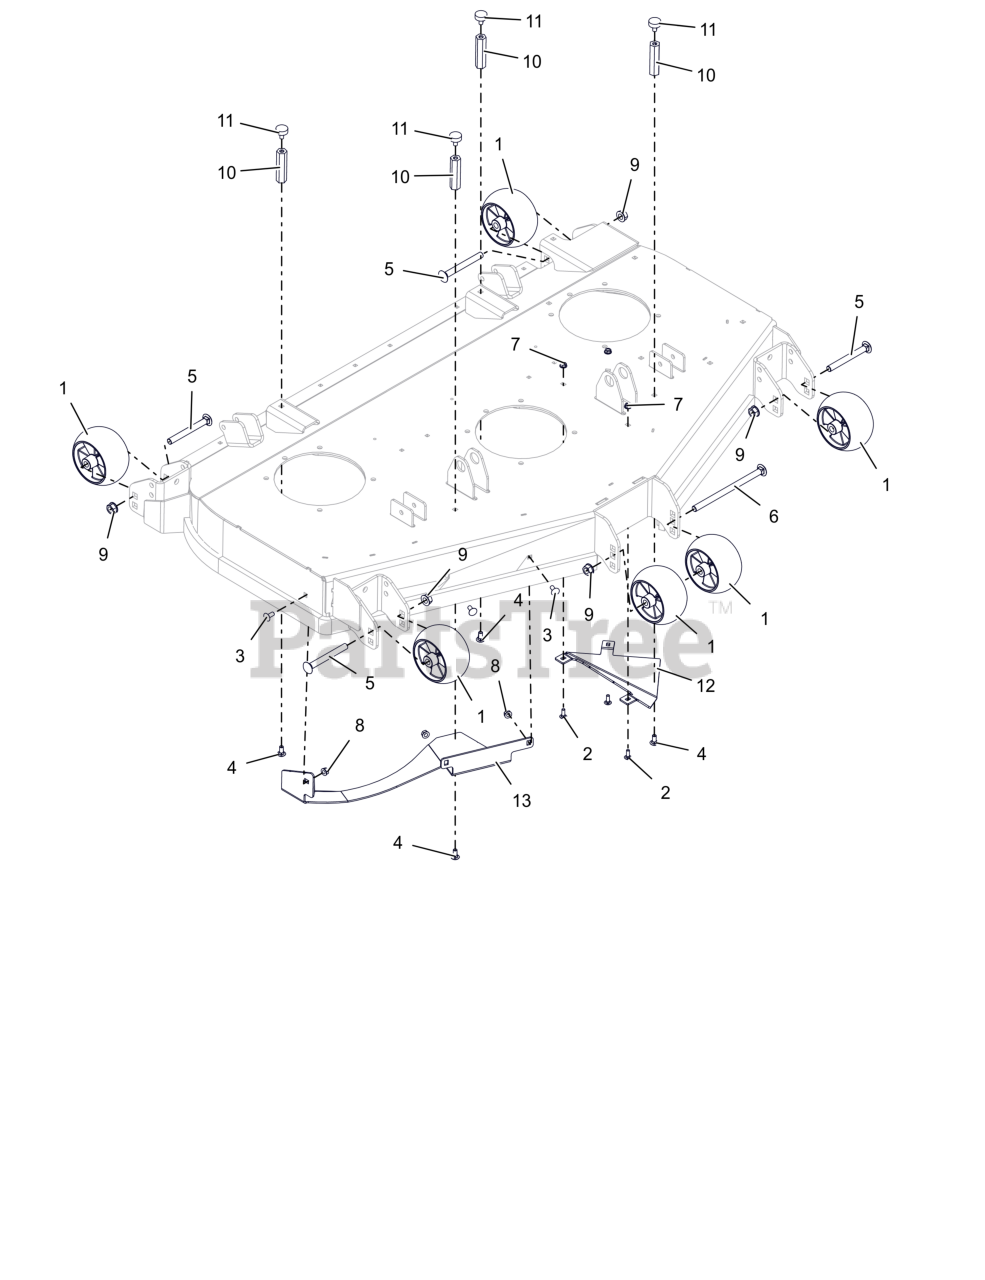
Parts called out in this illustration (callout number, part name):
1	WHEEL, ANTI SCALP - 5X3 CTR W/RIBS
2	BLT, RHSN .25-20X.750 G5 ZCC
3	BLT, RHSSN.31-18X.750 G5 ZCC
4	BTL,RHSN .313-18 X 0.75 G5 ZCC LT
5	BLT,RHNS .50-13X4.50 G5 ZCC NS
6	BLT,RHSN .50-13X8.00 G5 ZCC NS
7	NUT-LK-CTR-FLG .25-20 ZC120
8	NUT,LK-CTR-FLG .31-18 GF ZCC
9	NUT-LK-CTR-FLG .500-13 GG ZCC
10	NUT, COUPLING .31-18 X 3.00
11	BUMPER, RUBBER
12	BAFFLE- 52" TRIANGLULAR INSERT
13	DEFLECTOR- 52" BOLT-IN BAFFLE
